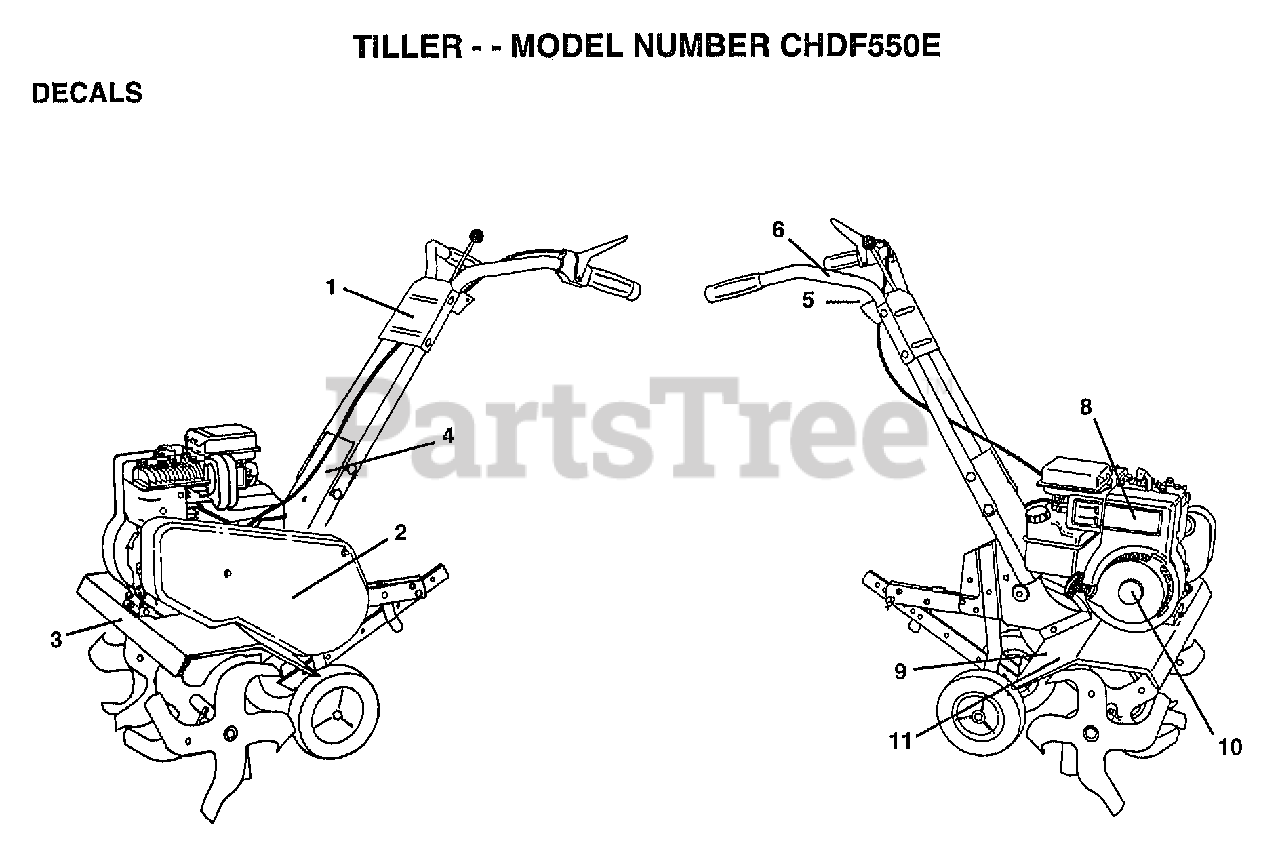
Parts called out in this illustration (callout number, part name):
1	"DECAL PANEL,CTRL"
3	"DECAL SHIELD,TINE"
4	"DECAL PANEL,FORWD"
5	DECAL REVERSE
6	DECAL TI
8	DECAL TI
11	DECAL.CAUTION
